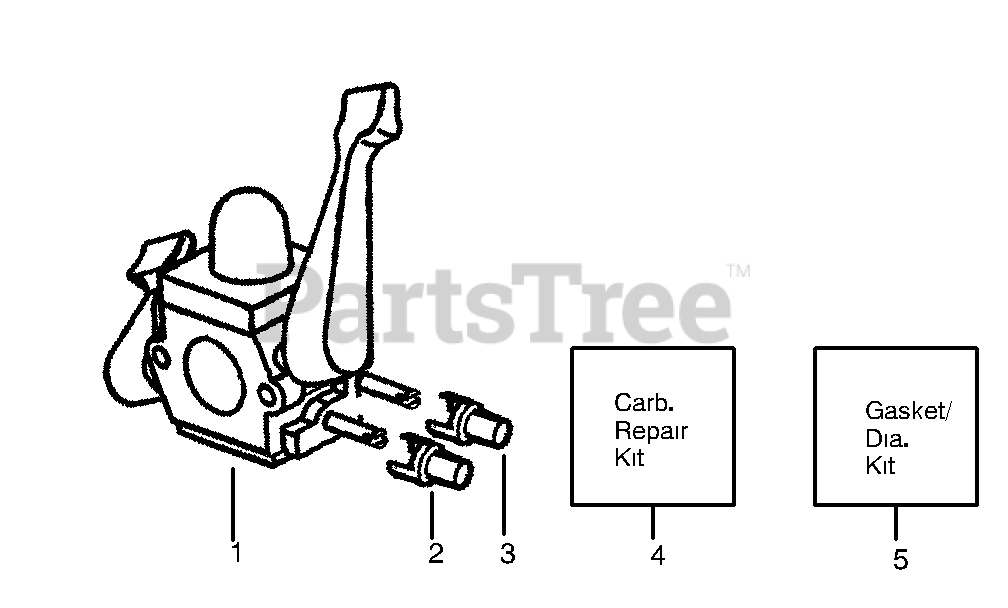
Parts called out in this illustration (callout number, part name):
1	Assy-Carb. Zama (C1Q-W11)
2	Cap-Limiter (high) brown
3	Cap-Limiter (low) tan
4	Kit-Carb. Repair
5	Kit-Carb. Gasket (Zama)
